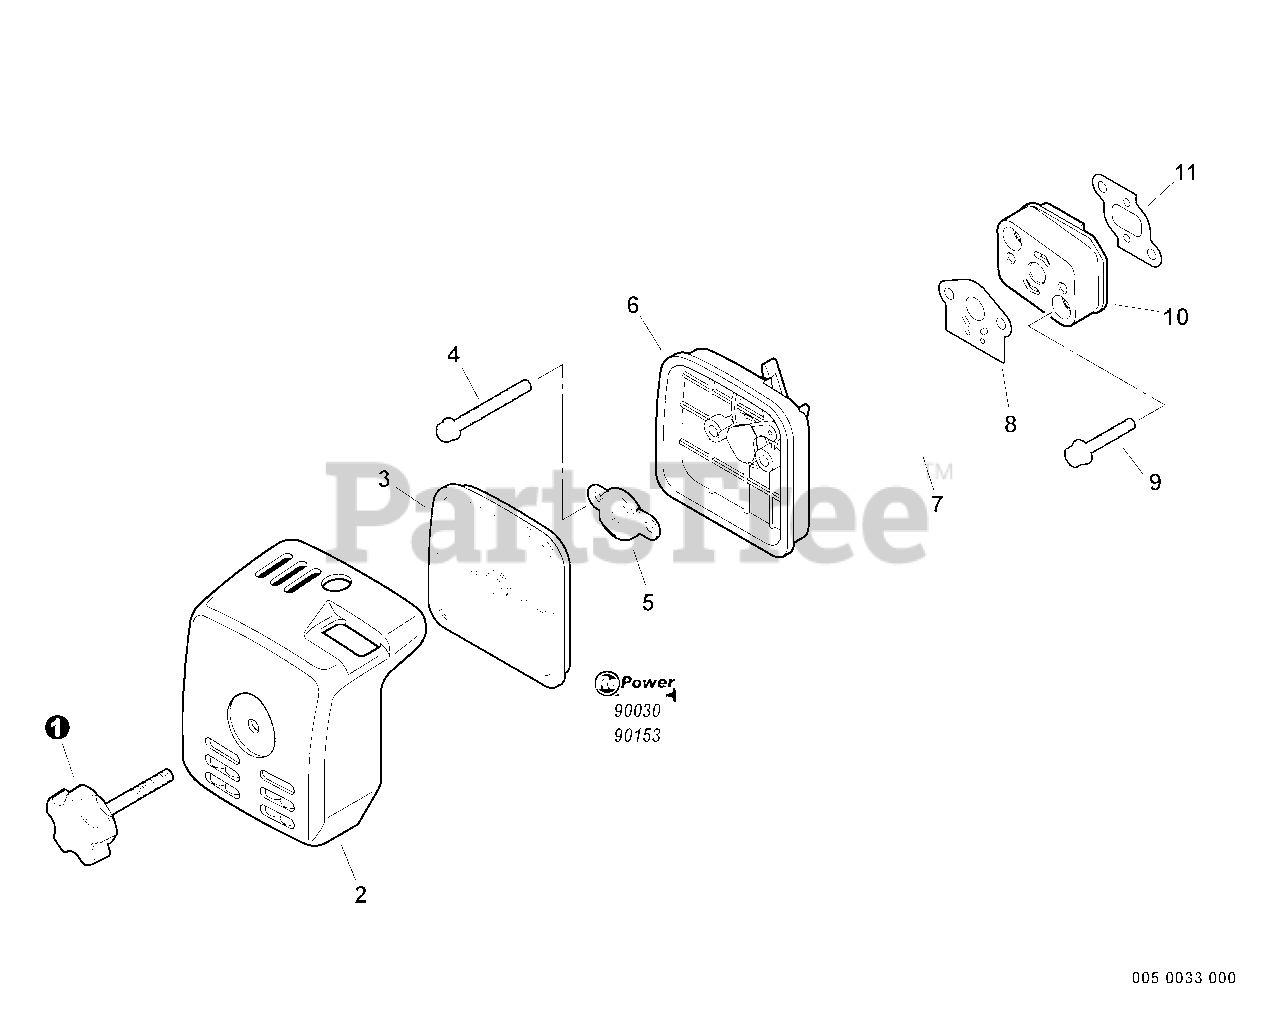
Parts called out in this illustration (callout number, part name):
1	THUMBSCREW
2	COVER, AIR FILTER
3	FILTER, AIR - HEAVY DUTY
4	SCREW - 5X60
5	PLATE, PREVENT
6	CASE, AIR FILTER
7	CARBURETOR
8	GASKET, INTAKE
9	SCREW - 5X25
10	INSULATOR, INTAKE
11	GASKET, INTAKE
12	RePower FILTER KIT
13	RePower TUNE-UP KIT
